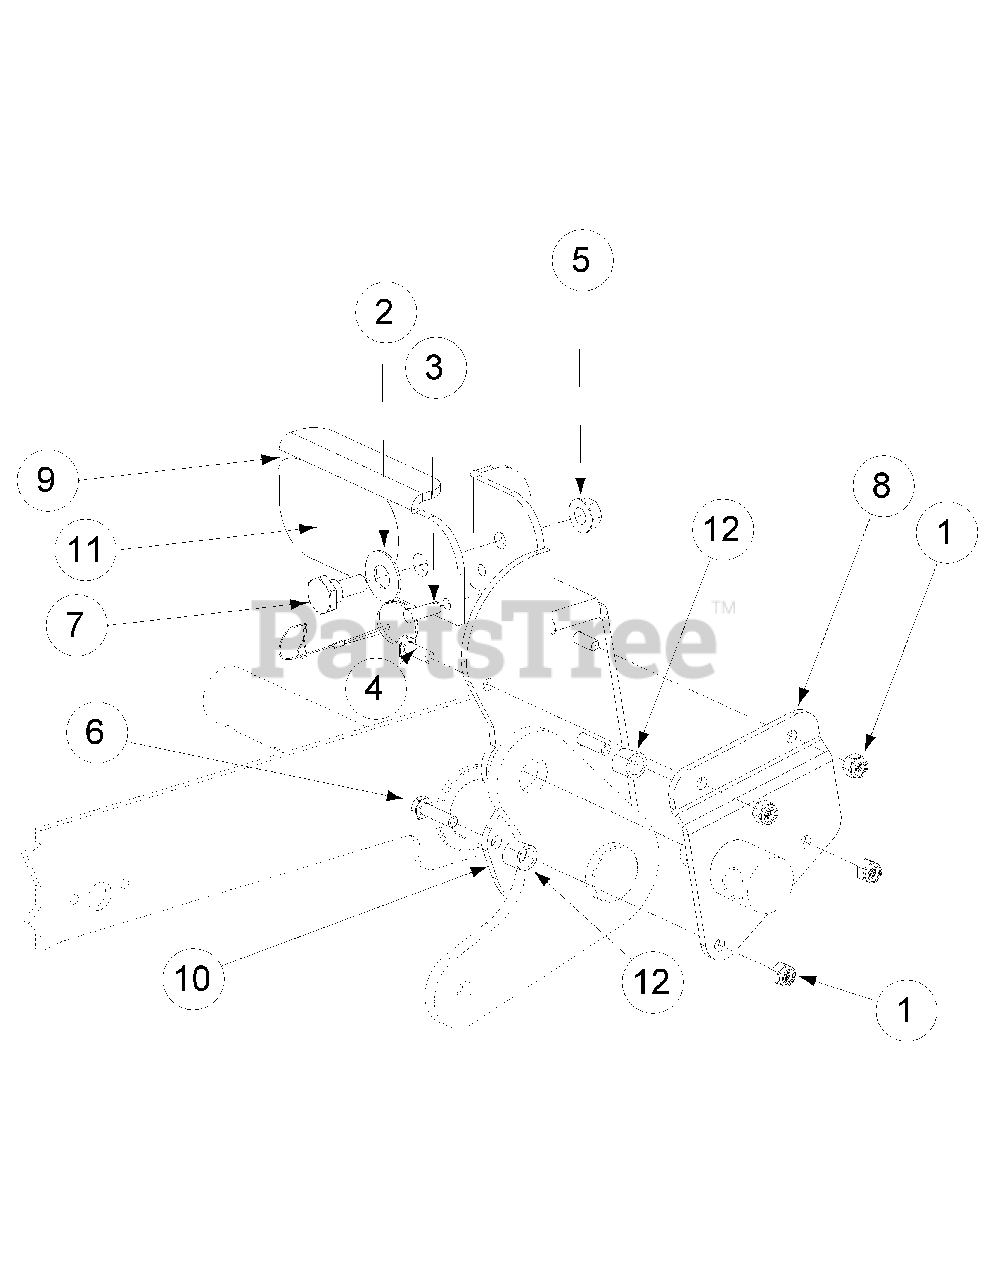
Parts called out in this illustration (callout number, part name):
1	Lock Nut, Nylon Insert, 1/4-20
2	Washer, 1/2 x 1 Shim
3	Detent Pin w/Lanyard, 1/4"
4	Hex Cap Screw, 1/4-20, .75
5	Hex Nut, Flange Lock 3/8-16
6	Hex Cap Screw, 1/4-20, 1.00
7	Shoulder Screw, .50x.27 Lg., 3/8-16
8	Foot Lift Backup Pedal
9	Deck Foot Pedal Lift
10	Deck Foot Pedal Lift Holder
11	Deck Foot Lift Pad
12	Turnbuckle Sleeve
